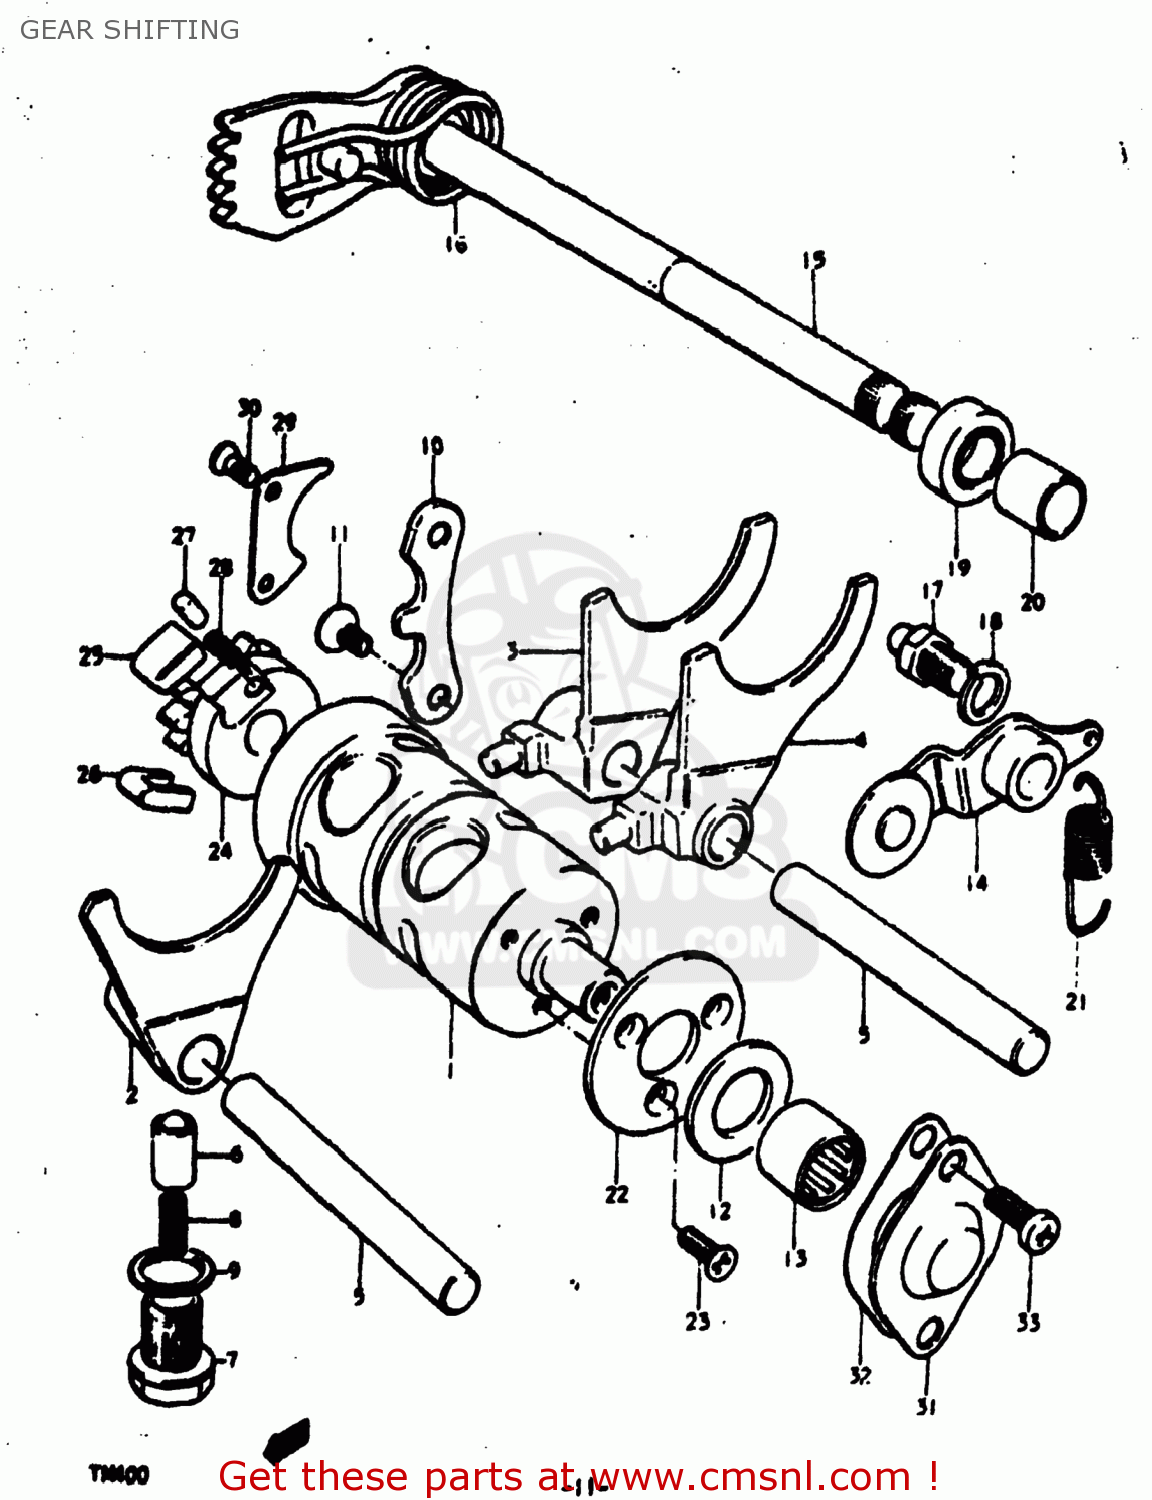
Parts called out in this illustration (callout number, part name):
1	CAM,GEAR SHIFT
2	FORK,GEAR SHIFT NO.1
3	FORK,GEAR SHIFT NO.2
4	FORK,GEAR SHIFT NO.3
5	SHAFT,GEAR SHIFT FORK
6	STOPPER,GEAR SHIFTING
7	BOLT,GEAR SHAFT CAM STOPPER
8	SPRING
9	GASKET(14X19.2X2) (NAS)
10	GUIDE,GEAR SHIFTING CABLE
11	SCREW
12	WASHER
13	ROLLER BEARING (12X18X1
14	STOPPER,GEAR SHIFTING
15	SHAFT,GEAR SHIFT
16	SPRING
17	STOPPER,GEAR SHIFT CAM
18	LOCK WASHER
19	OIL SEAL
20	CUSHION
21	SPRING
22	PLATE,GEAR SHIFT CAM
23	SCREW
24	RETAINER,GEAR SHIFT CAM
25	PAWL,GEAR SHIFT NO.1
26	PAWL,GEAR SHIFT NO.2
27	PIN(5X8)
28	SPRING
29	LIFTER,GEAR SHIFT PAWL
30	SCREW
31	CAP,CAM PIVOT
32	GASKET (MCA)
33	Screw
